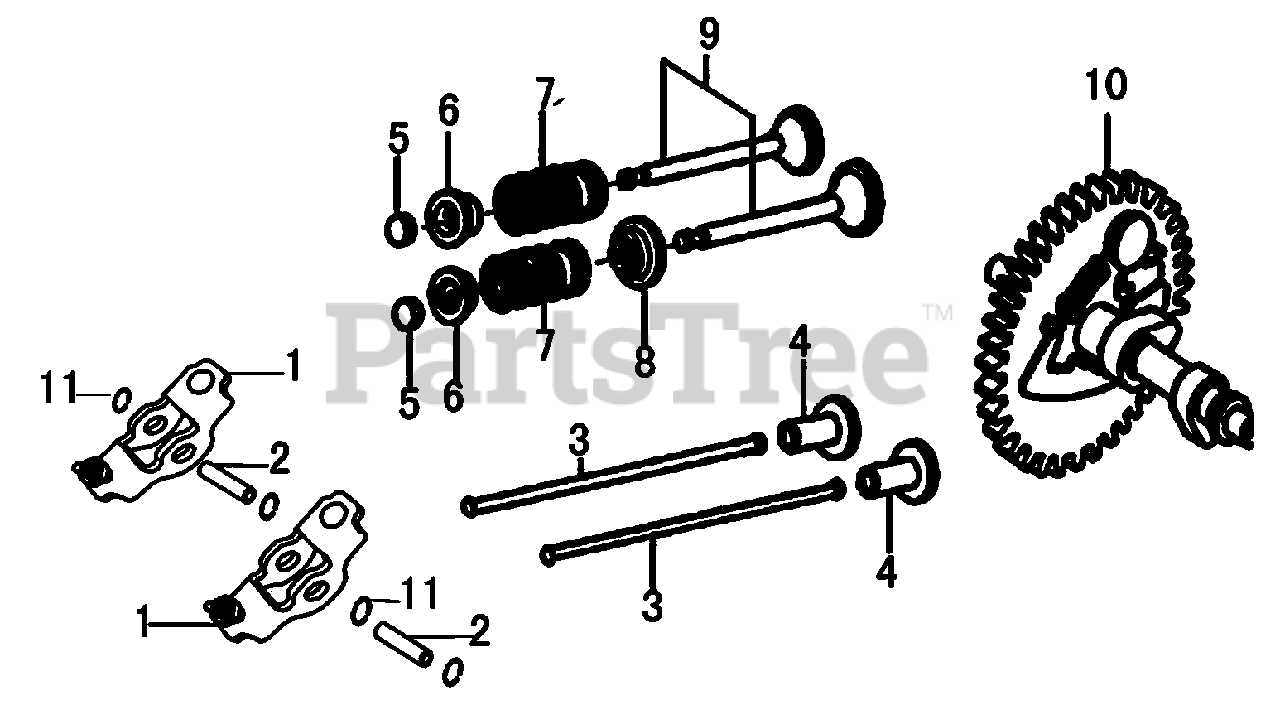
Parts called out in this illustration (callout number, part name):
1	ROCKER ARM
2	VALVE ROCKER SHAFT
3	ROD, PUSH
4	LIFTER VALVE
5	ROTATOR, VALVE
6	RETAINER, VALVE SPRING
7	SPRING, VALVE
8	SEAL, GUIDE
9	VALVE SET
10	CAMSHAFT ASSY
11	SPLIT WASHER
